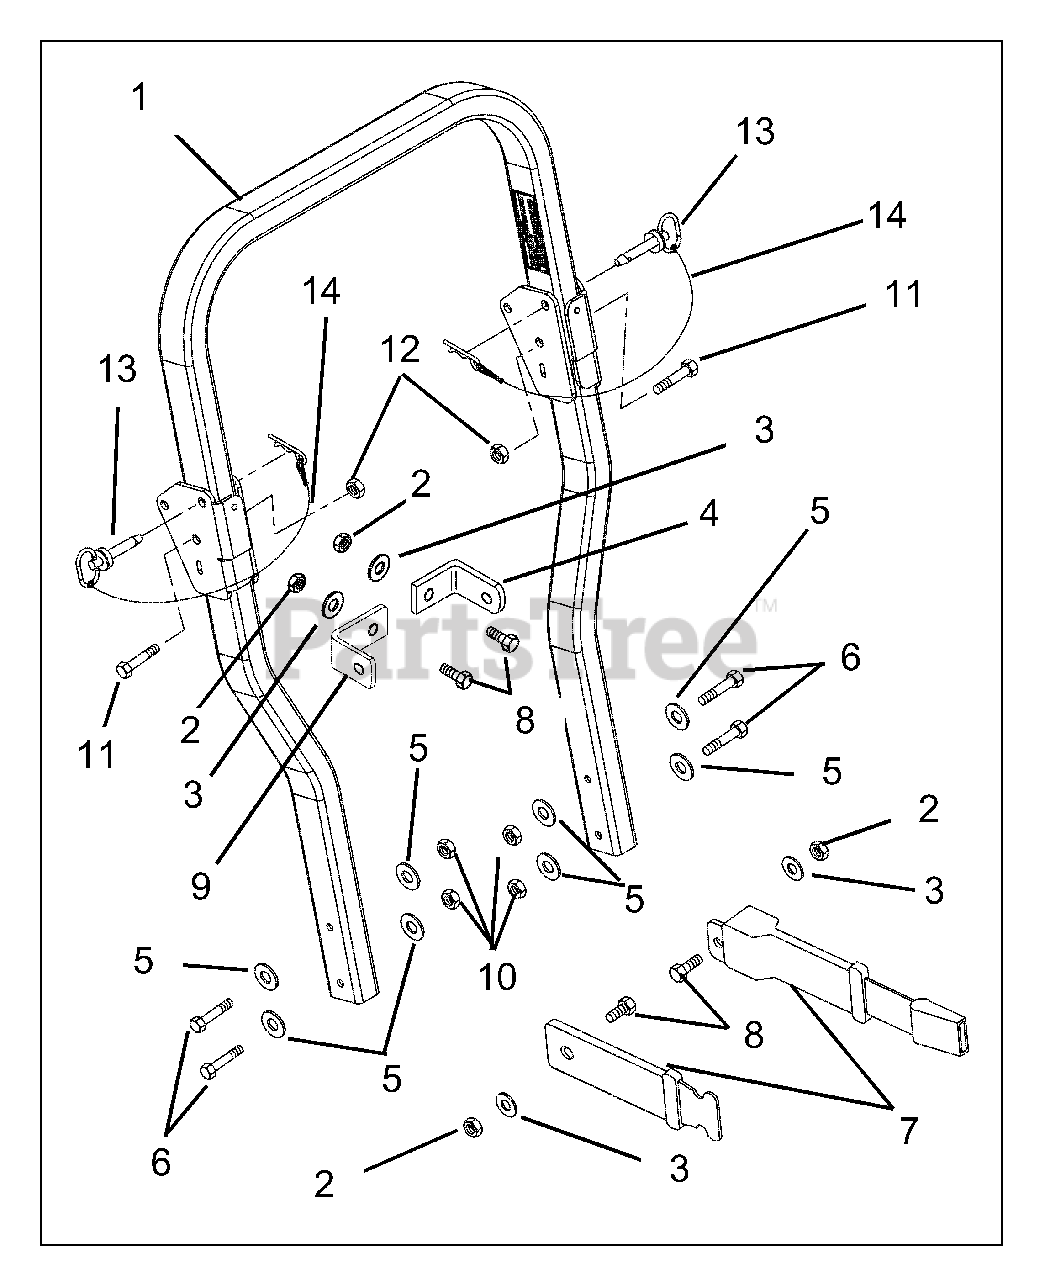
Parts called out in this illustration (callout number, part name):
1	Rollover Bar
2	Nylon Lock Nut, 7/16"-14
3	Flat Steel Washer,1/2" x 1-1/4" x 5/64"
4	Seat Belt Mount Bracket, Left Hand
5	Flat Steel Washer, 9/16" x 1-3/8" x 7/64"
6	Hex Bolt, 1/2"-13 x 3" Grade 5
7	Retractable Seat Belt
8	Hex Bolt, 7/16"-14 x 1" Grade 5
9	Seat Belt Mount Bracket, Right Hand
10	Lock Nut, 1/2"-13
11	Hex Bolt, 1/2"-13 x 3-1/4" Grade 5
12	Center Lock Nut, 1/2"-13
13	Hitch Pin with Hairpin
